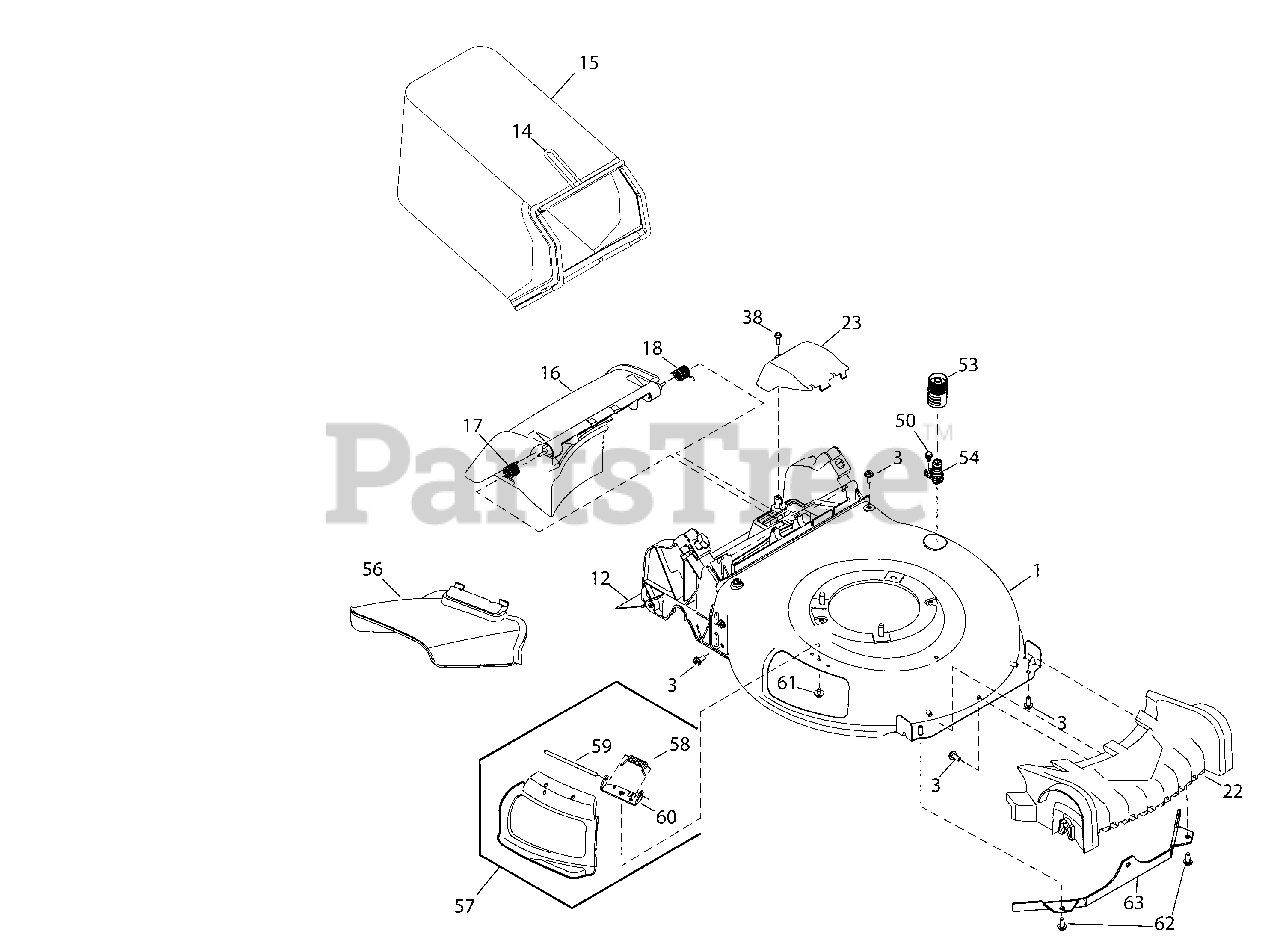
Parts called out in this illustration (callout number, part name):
3	SCREW, 5/16-14 x 3/4
12	SHIELD, Trailing
14	FRAME, Grass Bag
15	BAG, Grass
16	DOOR, Rear Discharge
17	SPRING, Torsion, RH
18	SPRING, Torsion, LH
22	COVER, Front
23	COVER, Transmission
38	SCREW, 1/4-15X3/4, Self-Tapping, BZ
50	BOLT, Shoulder, 1/4-20
53	ADAPTER, Water Nozzle
54	NOZZLE, Water
56	CHUTE, Side Discharge
57	MULCH PLUG
58	SPRING, Torsion
59	PIN, Hinge
60	BRACKET, Chute Deflector
61	SCREW, 1/4-20 x 1/2
62	SCREW, 5/16-14 x 1
63	BRACKET, Front Deck
